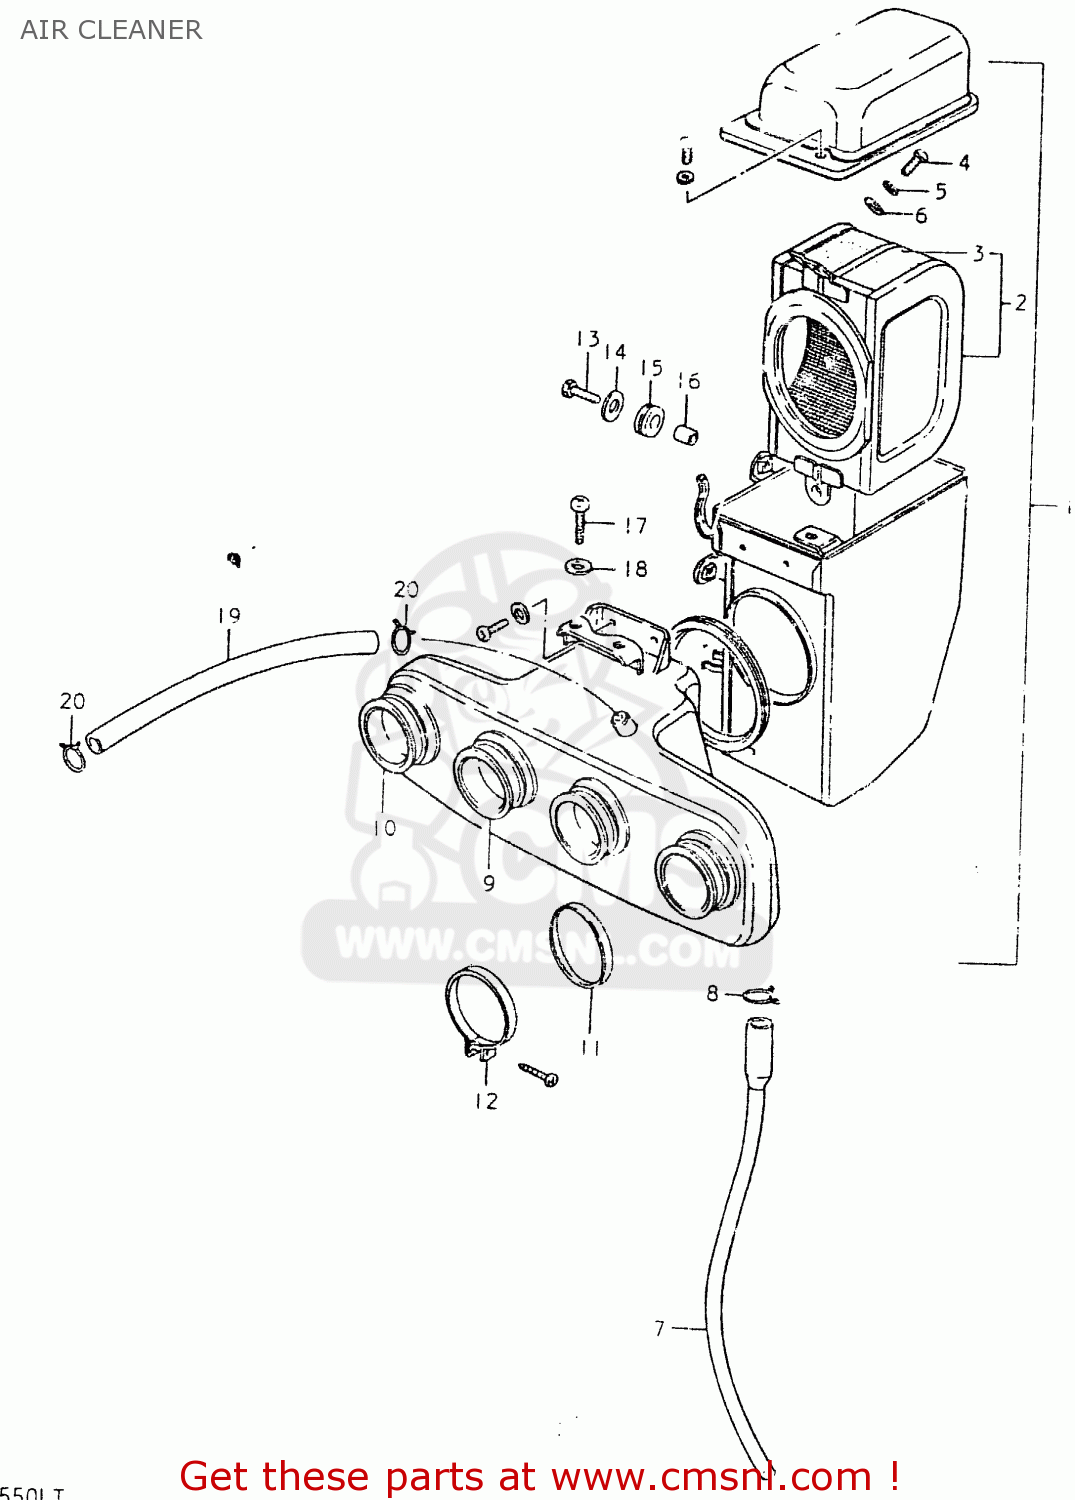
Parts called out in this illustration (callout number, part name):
1	CLEANER ASSY, AIR
2	FILTER ASSY
3	FILTER
4	SCREW
5	LOCK WASHER
6	WASHER
7	HOLDER,FILTER
8	CLIP
9	TUBE,AIR CLEANER OUTLET A
10	TUBE,AIR CLEANER OUTLET B
11	RING,CARBURETOR AIR INLET HOSE
12	CLAMP
13	BOLT
14	WASHER
15	CUSHION
16	SPACER (6.1X9X9)
17	SCREW 6X12
18	WASHER
19	HOSE
20	CLIP
